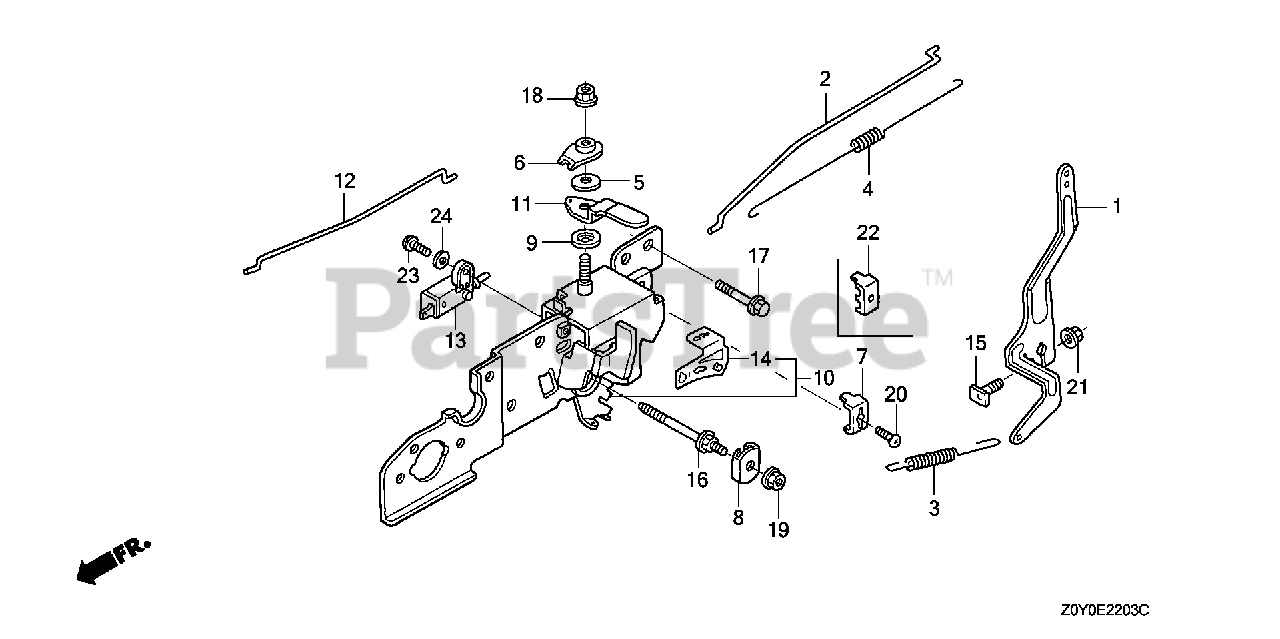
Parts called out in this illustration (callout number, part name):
1	ARM, GOVERNOR
2	ROD, GOVERNOR
3	ROD, GOVERNOR
3	SPRING, GOVERNOR
4	SPRING, THROTTLE RETURN
5	SPRING, LEVER
6	WASHER, CONTROL LEVER
7	HOLDER, CABLE
8	PLATE, LEVER CENTER
9	SPACER, CONTROL LEVER
10	BASE, CONTROL
11	LEVER, CHOKE
12	ROD, CHOKE
13	SWITCH ASSY., ENGINE STOP (N.O)
14	MARK, THROTTLE INDICATION
15	BOLT, GOVERNOR ARM
16	BOLT, SPECIAL (6X45)
17	BOLT, FLANGE (6X32)
18	NUT, SELF-LOCK (6MM)
19	NUT, SELF-LOCK (5MM)
20	SCREW, PAN (5X16)
21	NUT, FLANGE (6MM)
22	HOLDER, CABLE
23	SCREW-WASHER (4X12)
24	WASHER, PLAIN (4MM)
